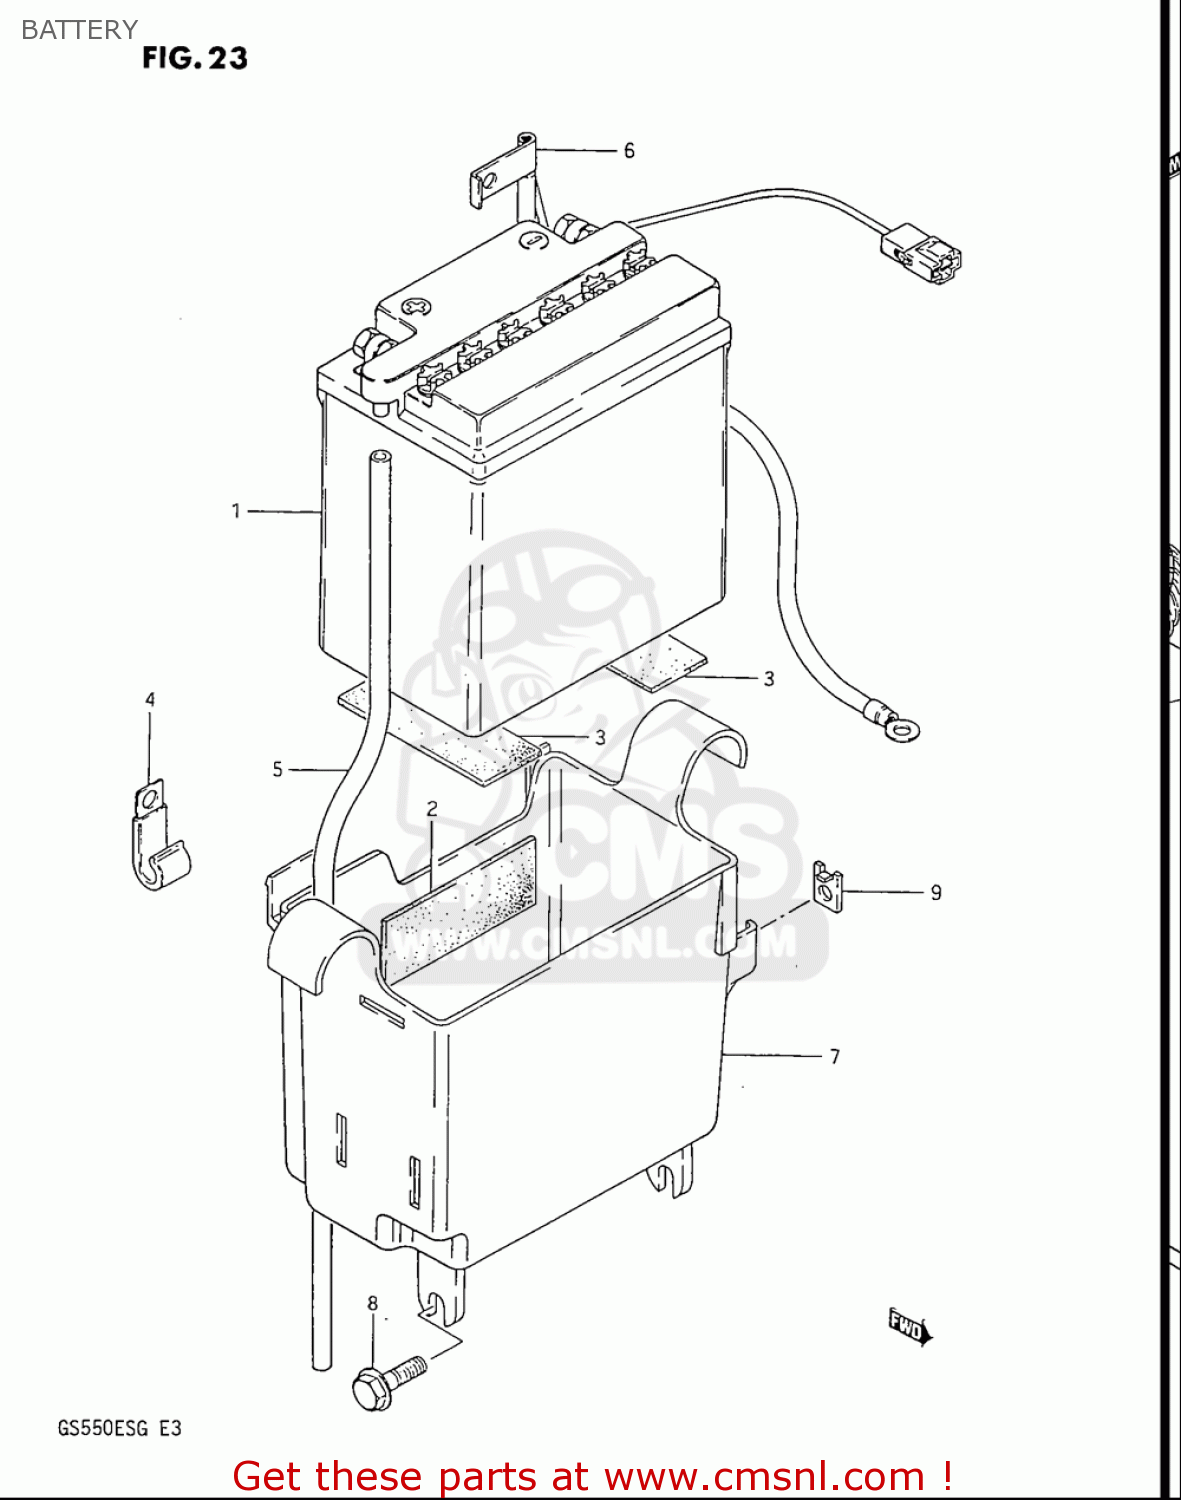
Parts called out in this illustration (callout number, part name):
1	BATTERY(YB10L-B,12V12AH)
2	PROTECTOR(80X80X2)
3	PROTECTOR(170X95X3.0)
4	CLAMP
5	HOSE,BATTERY EXHAUST(L:780)
6	WIRE,BATTERY MINUS LEAD
7	HOLDER,BATTERY
8	BOLT
